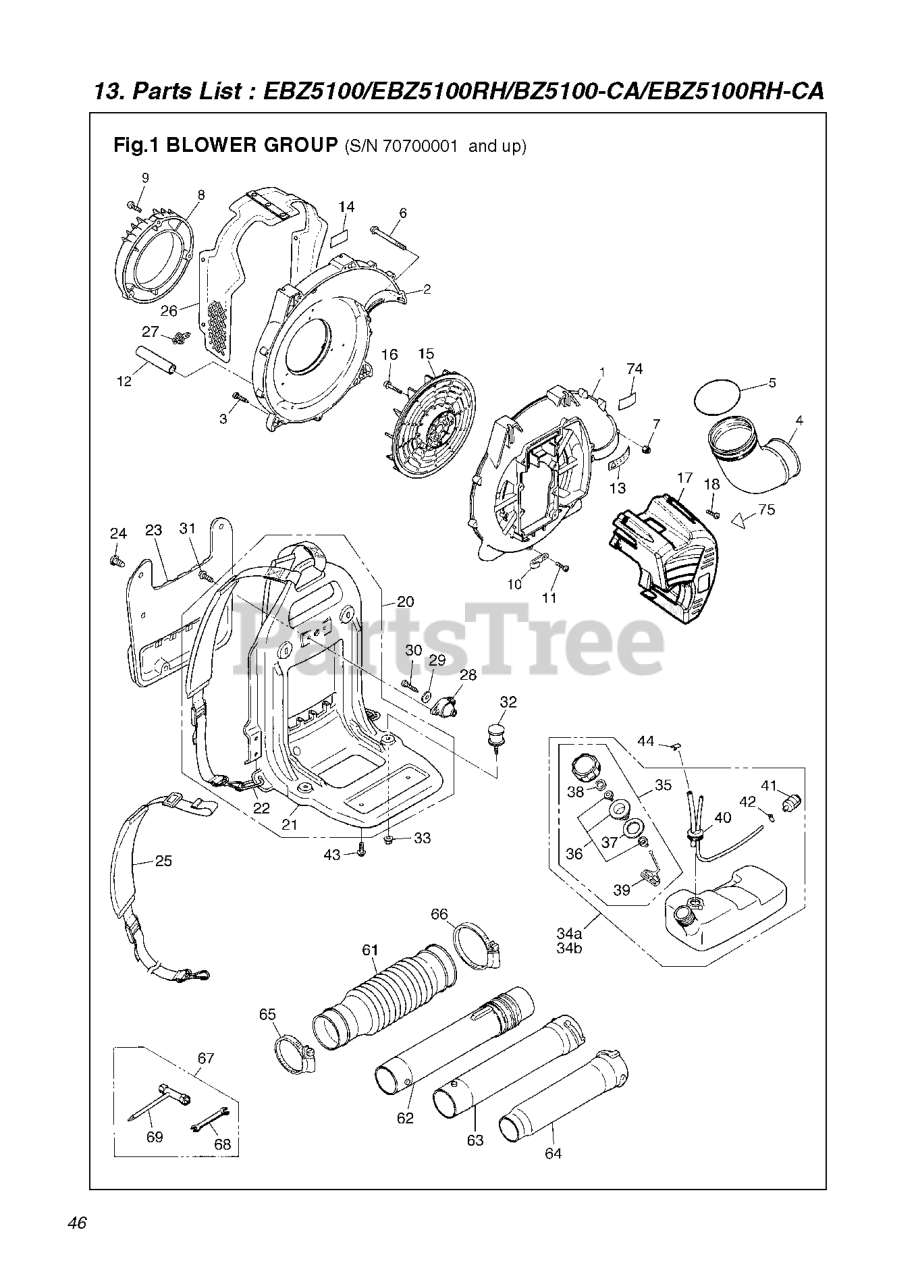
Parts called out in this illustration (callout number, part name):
1	VOLUTE CASE
2	VOLUTE COVER
3	SCREW
4	PIPE BEND
6	BOLT,TORX, M5X70
7	RP_NUT (B)
9	SCREW
10	CLAMP (BT Only)
12	RP_TUBE (RPLS 0727001507)
13	LABEL, CAUTION(RPLS 275031910)
14	LABEL, NET
17	ENGINE COVER
18	SCREW
20	FRAME ASSY(RPLS -3500,-3501)
21	FRAME COMP.
22	RING (RPLS 349021120)
24	CLIP (RPLS 3490-21320)
25	BAND ASSY. (BUCKLE 275632910)
26	NET COMP (RPLS-T402325430)
27	CLIP
28	DAMPER
29	WASHER
30	SCREW (RPLS T497054010)
32	DAMPER
33	NUT (M6)
34A	TANK ASSY.
35	ASSY FUEL CAP
36	HOLDER (RPLS 450085230)
37	PACKING
38	FILTER
40	PIPE COMPLETE
41	FILTER ASSY EXT WHITECAP
42	CLIP
44	CLIP
61	BELLOWS
62	SWIVEL JOINT (RP 275051200)
63	PIPE, STRAIGHT(RPLS 681151210)
64	PIPE, END RPLS 848L0L65E0
65	CLAMP***
66	CLAMP***
67	TOOL-SET
68	SPANNER,8x10(RPLS 090100810
69	SOCKET
75	RP_LABEL, HOTMARK
